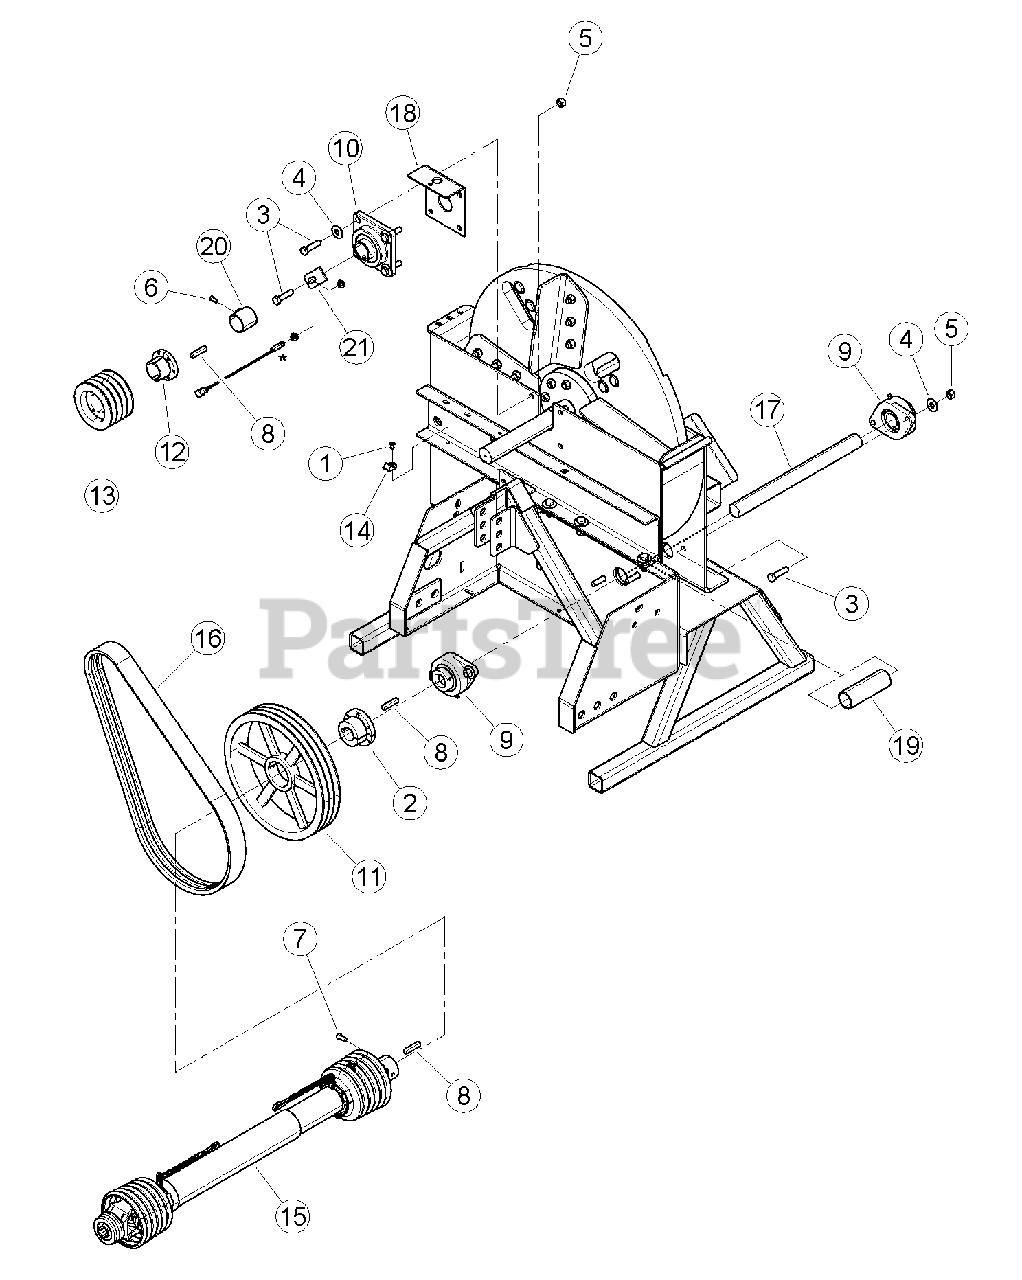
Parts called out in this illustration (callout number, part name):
1	RIVET, 1/4 X 3/4 ST POP
2	BUSHING, SK 1-1/2
3	BOLT, 1/2 X 2 HEX GR5 ZP
4	WASHER, 1/2 FLAT ZP
5	NUT, 1/2 CENTERLOCK GRB ZP
6	SCREW, 5/16-18 X 5/8 SQ HD SET
7	SCREW, 3/8 X 3/4 SQ HD SET ZP
8	KEY, 3/8 SQUARE X 2 LONG PLAIN
9	BEARING,2 BOLT FLANGE 1-1/2 BORE
10	BEARING, 1-3/4 4 BOLT FLANGE
11	SHEAVE, 3B13.6 SK
12	BUSHING, SD 1-3/4
13	SHEAVE, 4BQ4.8 SD
14	CLAMP, CABLE MOUNT
15	DRIVELINE, 33.9/47.6 1-1/2 RND/1-3/8 6 SPL
16	BELT, 3RB64
17	JACKSHAFT, CHIPPER DRIVE
18	WELDMENT, LEFT BEARING BRACKET
19	SHIELD, SHAFT
20	WELDMENT, SPACER
21	BRACKET, SENSOR SHORT MOUNT
